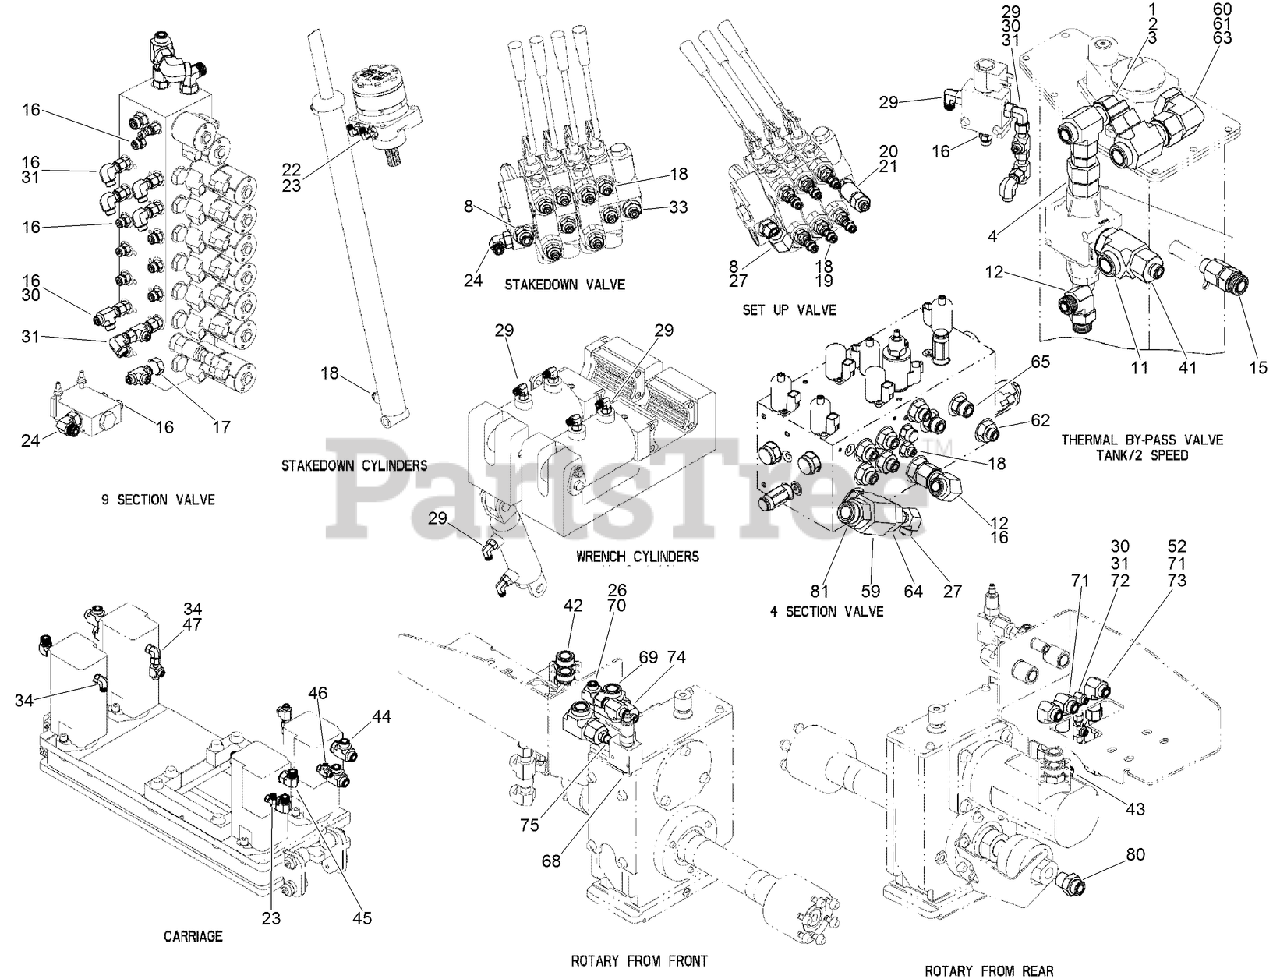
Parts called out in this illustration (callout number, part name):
1	CONNECTION - Straight, -12 ORFS / -8 ORB
2	FITTING-TEE
3	CONNECTION - Adapter, -12 ORB / -12 ORFS
4	FITTING-STRAIGHT
8	CONNECTION - Straight, -8 ORFS / -10 ORB
11	CONNECTION - Run Tee, -16 ORFS / -16 ORB
12	CONNECTION - Straight, -12 ORFS / -16 ORB
15	FITTING-STRAIGHT
16	CONNECTION - Straight, -4 ORFS / -6 ORB
17	FITTING-STR,ORIF
18	CONNECTION - Straight, -4 ORFS / -8 ORB
19	FITTING-STRAIGHT
20	CONNECTOR
21	CONNECTION - 90 Degree, -4 ORFS / -4 ORB
22	REDUCER-STRAIGHT, THREADED
23	CONNECTION - 90 Deg, -4 ORFS / -4 ORB
24	CONNECTION - 90 Deg, -6 ORFS / -8 ORB
26	CONNECTION - Run Tee, -8 ORFS / -8 ORFS
27	CONNECTION - 90 Deg, -8 ORFS / -8 ORFS
29	CONNECTION - 90 Deg, -4 ORFS / -6 ORB
30	CONNECTION - Run Tee, -4 ORFS / -4 ORFS
31	CONNECTION - 90 Deg, -4 ORFS / -4 ORFS
33	CONNECTION - Straight, -6 ORFS / -10 ORB
34	CONNECTION - 90 Deg, -6 ORFS / -6 ORB
41	FITTING-REDUCER
42	CONNECTION - Straight, -16 ORFS / -16 ORB
43	CONNECTION - Straight, -8 ORFS / -6 ORB
44	CONNECTION - Run Tee, -10 ORFS / -10 ORB
45	CONNECTION - 90 Deg, -10 ORFS / -10 ORB
46	CONNECTION - Run Tee, -4 ORFS / -4 ORB
47	CONNECTION - Run Tee, -6 ORFS / -6 ORFS
52	FITTING-TEE
59	FITTING-TEE
60	CONNECTION - 90 Degree, -16 ORFS / -20 ORB
61	FITTING-TEE
62	CONNECTION - Straight, -8 ORFS / -12 ORB
63	FITTING-REDUCER
64	FITTING-REDUCER
65	CONNECTION - Straight, -10 ORFS / -12 ORB
68	CONNECTION - Straight, -6 ORFS / -6 ORB
69	FITTING-TEE, BULKHEAD
70	CONNECTION - Run Tee, Bulkhead, -8 ORFS / -8 ORFS
71	CONNECTION - 90 Degree, Bulkhead, -10 ORFS / -10 ORFS
72	CONNECTION - 90 Degree, Bulkhead, -4 ORFS / -4 ORFS
73	CONNECTION - 90 Degree, -10 ORFS / -10 ORFS
74	FITTING-REDUCER
75	CONNECTION - Straight, -6 ORFS / -6 ORB
80	CONNECTION - Straight, -12 ORFS / -16 ORB
81	CONNECTION - Reducer, ORFS / ORFS
